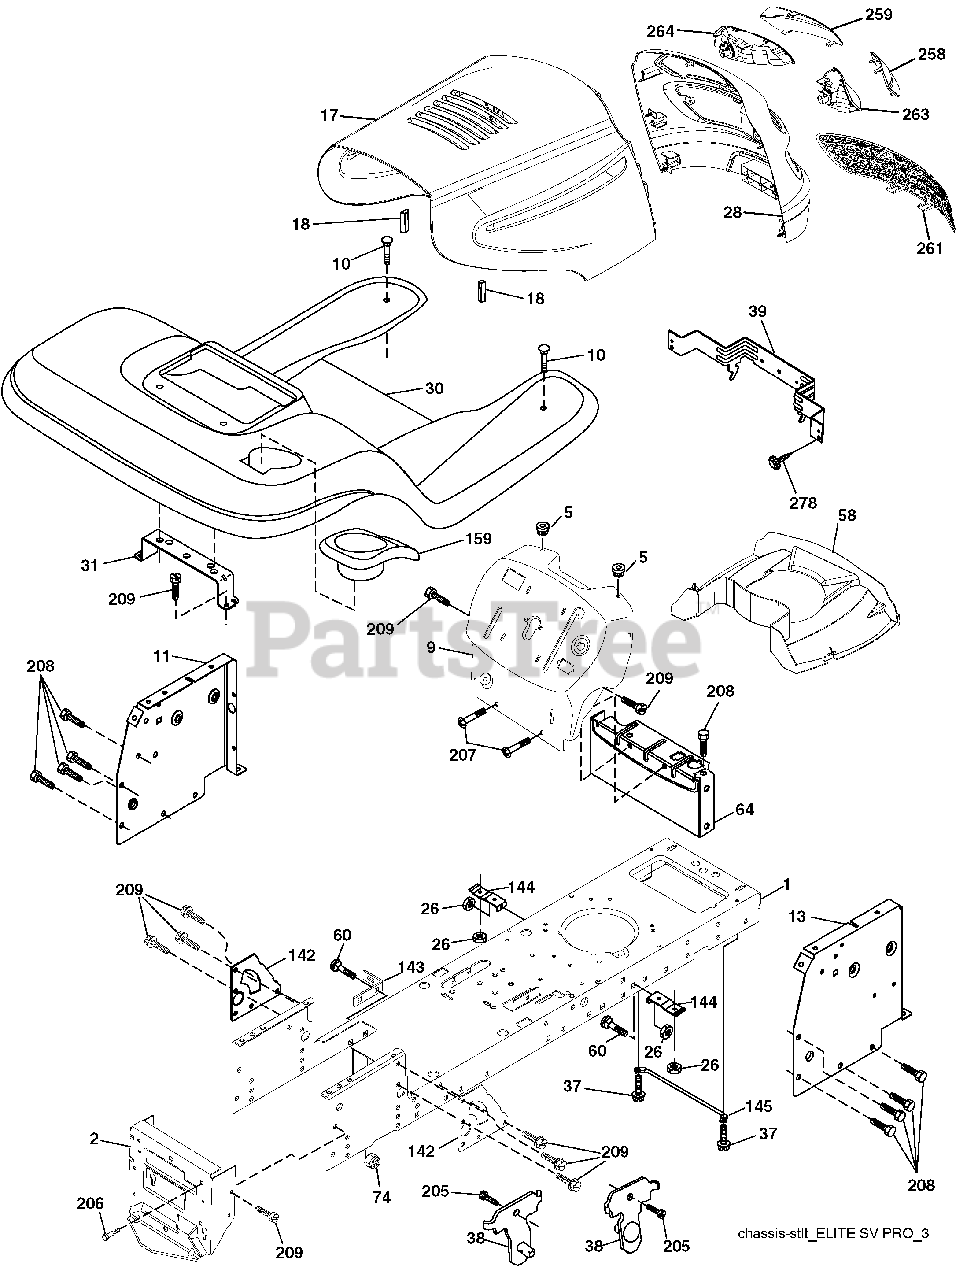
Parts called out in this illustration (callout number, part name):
1	Chassis
2	Drawbar
5	Bumper Hood/Dash
9	Dash P/L
10	Bolt Carriage 3/8-16 x 1
11	Panel Dash LH
17	Hood
18	Bumper Hood
26	Nut Lock Hex w/Ins 3/8-16 unc
28	Grille/Lens Asm
31	Bracket Fender
37	Screw Thdrol 6/16-18 x 1/2 TYT
38	Bracket Asm Pivot Mower Rear
39	Bracket Pivot
58	Duct Air
60	Bolt RDHD SQNK 3/8-16 unc x 1
64	Dash Lower STLT
74	Nut Crownlock 3/8-16 unc
142	Plate Reinforcement STLT
143	Bracket Swaybar Chassis
144	Bracket Footrest
145	Rod Pivot Chassis/Hood
159	Cupholder
205	Screw THDROL 3/8-16 x 1/2
206	Bolt Shoulder 5/16-18
207	Screw Thdrol 5/16-18 x 1/2
208	Screw Thdrol 3/8-16 x 1/2
209	Screw Hexwsh Thdr 3/8-16 x 3/4
258	Lens Grille Pro RH
259	Lens Grille Pro LH
263	Bezel Grille RH
264	Bezel Grille LH
278	Screw #10 x 0.750 BOS Thread
278	Plug BTN BlK
278	Plug Domed Plastic
